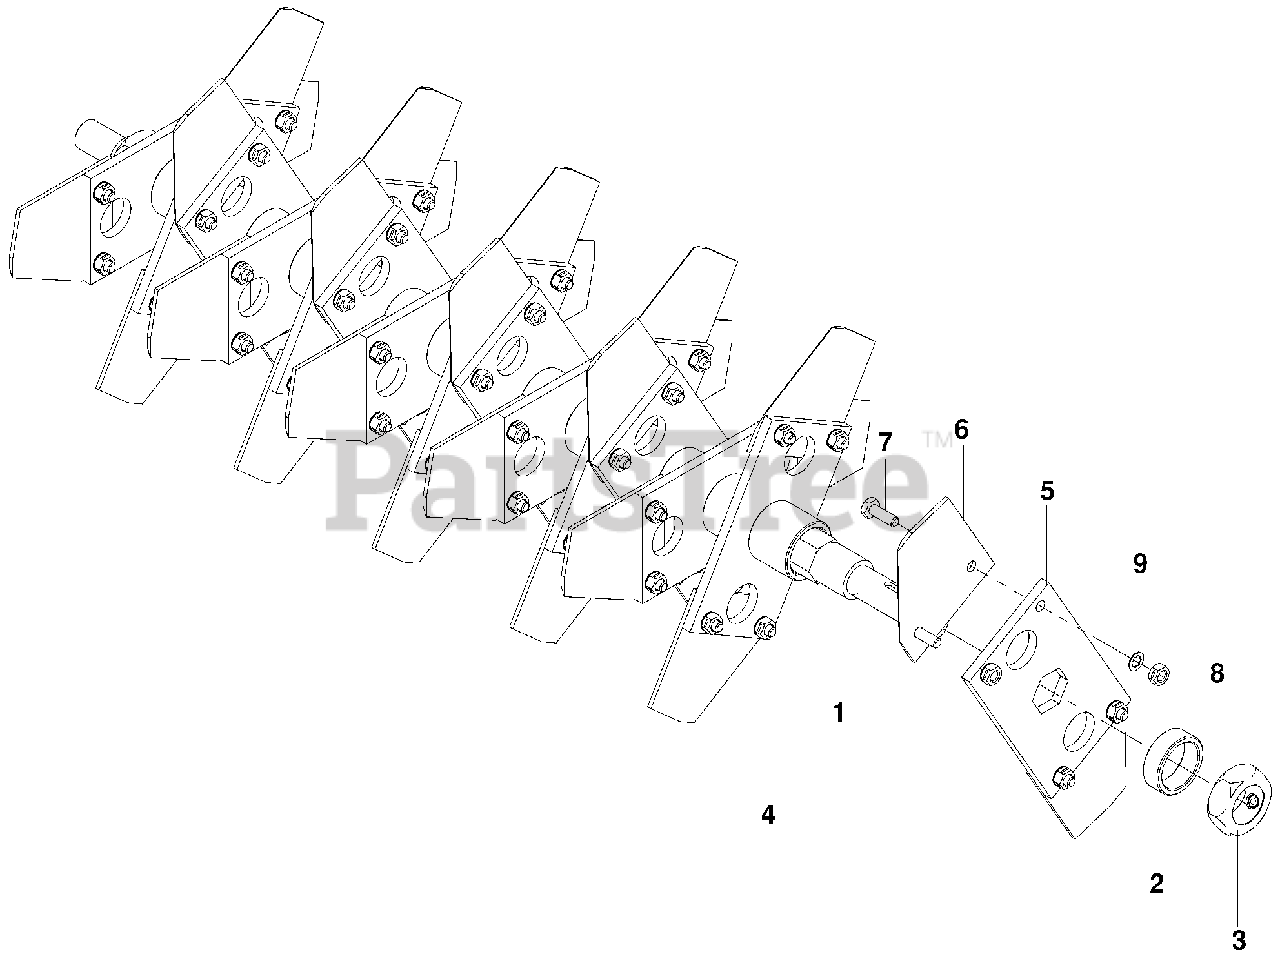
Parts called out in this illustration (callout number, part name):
1	DELTA SHAFT
2	END SPACER
3	JAM NUT w/ SET SCREW
4	SPACER-LONG
5	BLADE PLATE
6	DELTA BLADE
7	HCS ¼-20 x ¾ GR8
8	NUT ¼-20 CTRLK
9	WASHER ¼ LK INTNL TOOTH
